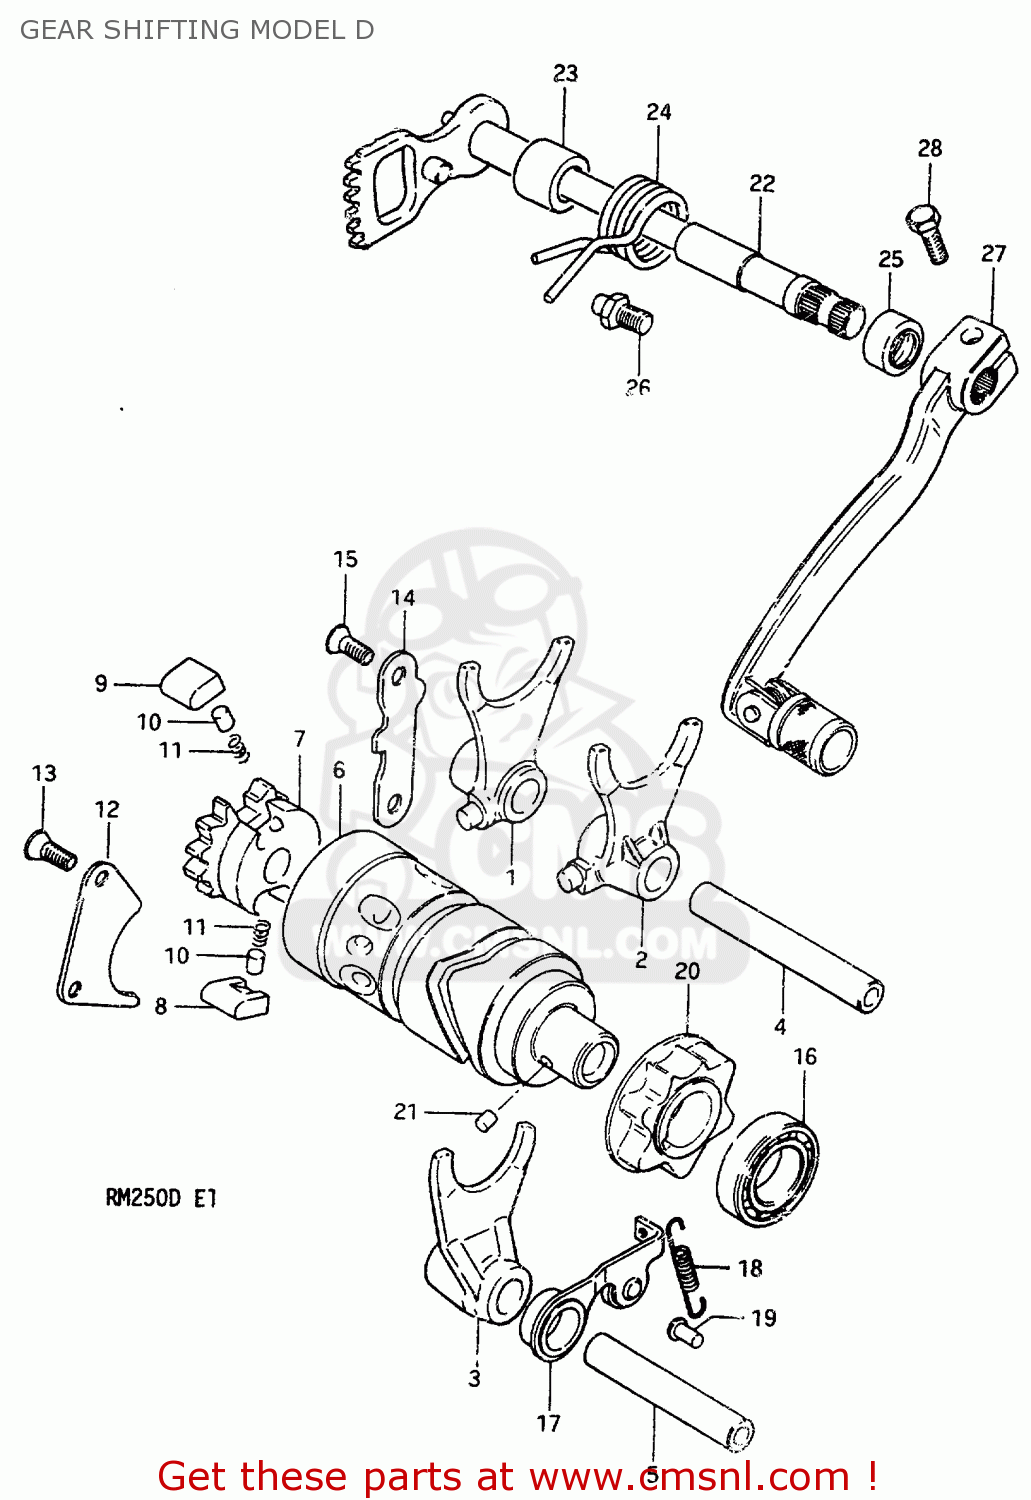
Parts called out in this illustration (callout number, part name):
1	FORK,GEAR SHIFT NO.1
2	FORK,GEAR SHIFT NO.2
3	FORK,GEAR SHIFT NO.3
4	SHAFT,GEAR SHIFT FORK
5	SHAFT,GEAR SHIFT FORK NO.2
6	CAM,GEAR SHIFT
7	GEAR,GEARSHIFT CAM DRIVE
8	PAWL,GEAR SHIFT NO.1
9	PAWL,GEAR SHIFT NO.2
10	PIN(5X8)
11	SPRING
12	LIFTER,GEAR SHIFT PAWL
13	SCREW
14	GUIDE,GEAR SHIFTING CABLE
15	SCREW
16	BEARING
17	STOPPER,GEAR SHIFTING CAM
18	SPRING
19	OIL PUMP LEVER PIN
20	PLATE,GEAR SHIFT CAM STOPPER
21	PIN 4X6
22	SHAFT,GEAR SHIFT
23	SPACER(12X20X15.3)
24	SPRING
25	OIL SEAL
26	STOPPER,GEAR SHIFT CAM
27	LEVER ASSEMBLY,GEAR SHIFTING
28	BOLT 6X35
